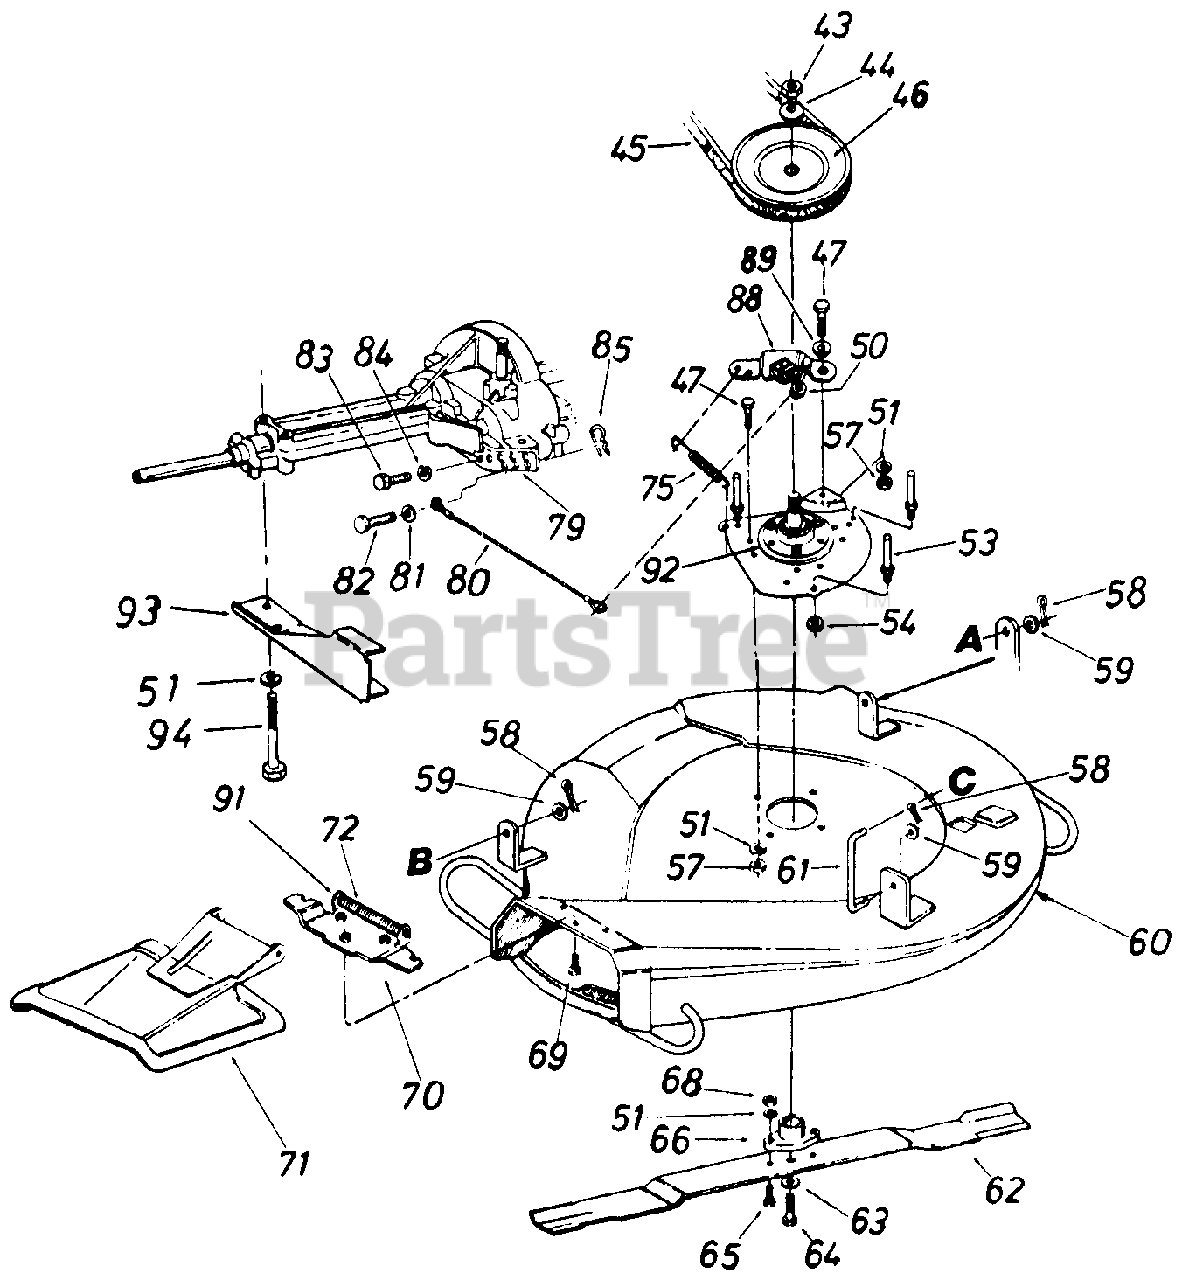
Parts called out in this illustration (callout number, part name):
43	Hex Jam Nut 5/8-18 Thd.
44	Bell-Wash. .63" I.D. x 1.25" O.D.
45	V-Belt 1/2 x 52" Lg.
46	1/2" V-Pulley .625" I.D. x 6.0" O.D.
47	Hex Bolt 5/16-18 x .75
50	Cap Speed Nut 1/4" Rod
51	L-Wash. 5/16" I.D.*
53	Stud 3/8-16 x 3.00" Lg.
54	Hex Jam Nut 3/8-16 Thd.
57	Hex Nut 5/16-18 Thd.*
58	Intern. Cotter Pin 1/2" Dia.
59	Fl-Wash. .385" I.D. x .87"
60	26" Deck Ass'y.
61	Deck Link 3.9" Lg.
62	26" High Lift Blade
63	Bell-Wash. .39" I.D. x 1.38"
64	Hex Bolt 3/8-24 x 1.0"*
65	Hex Bolt Spec. 5/16-24 x 1.0" Lg.
66	Blade Adapter
68	Hex Nut 5/16-24 Thd.*
69	Hex Wash. S-Tap Scr. 1/4-20 x .50" Lg.
70	Adapter Plate-Chute
71	Chute Cover Ass'y. Comp.
72	Torsion Spring
75	Extension Spring 3.25" Lg.
79	Lower Inside Belt Guard
80	Brake Cable 11.75" Lg.
81	Fl-Wash. .281" I.D. x .50"
82	Clevis Pin 1/4" Dia. x .53" O.D.
83	Hex Bolt 1/4-20 x .62" Lg.
84	L-Wash. 1/4" I.D.*
85	Intern. Cot.-Pin 5/16" Dia.
88	Blade Brake Brkt. Ass'y.
89	Shld. Spacer .27" Lg.
91	Hinge Pin
92	Blade Spindle Ass'y. Comp.
93	Lower Outside Belt Guard
94	Hex Bolt 5/16-18 x 2.5" Lg.
